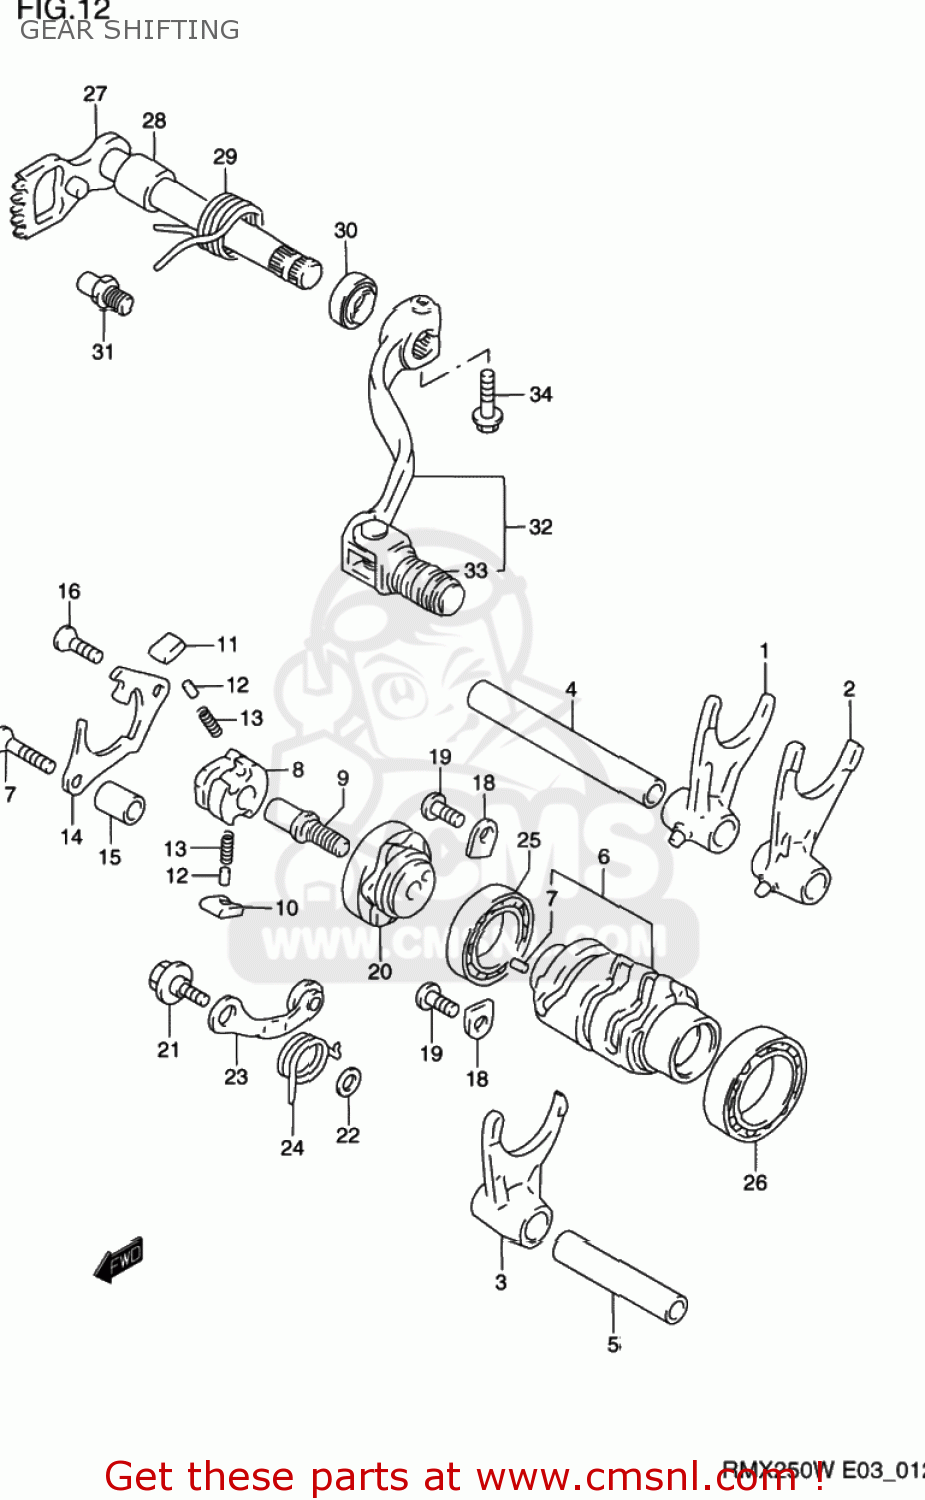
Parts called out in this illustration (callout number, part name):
1	FORK,GEAR SHIFT NO.1
2	FORK,GEAR SHIFT NO.2
3	FORK,GEAR SHIFT NO.3
4	SHAFT,GEAR SHIFT FORK
5	SHAFT,GEAR SHIFT FORK
6	CAM,GEAR SHIFT
7	PIN
8	GEAR,GEARSHIFT CAM DRIVE
9	PIN,SHIFT CAM DRIVEN GEAR
10	PAWL,GEAR SHIFT NO.1
11	PAWL,GEAR SHIFT NO.2
12	PIN(5X8)
13	SPRING
14	LIFTER,GEAR SHIFT POLE
15	SPACER(6.2X12X18)
16	SCREW
17	SCREW
18	RETAINER
19	SCREW
20	PLATE,SHIFT CAM STOPPER
21	BOLT(6X14.3)
22	WASHER
23	STOPPER,SHIFT CAM
24	SPRING
25	BEARING
26	BEARING(30X37X12)
27	SHAFT,GEAR SHIFT
28	SPACER(14X20X17.5)
29	SPRING
30	SEAL,OIL(14X22X6)
31	STOPPER,GEAR SHIFT CAM
32	LEVER ASSEMBLY,GEAR SHIFTING
33	RUBBER,GEAR SHIFT PEDAL
34	SCREW
